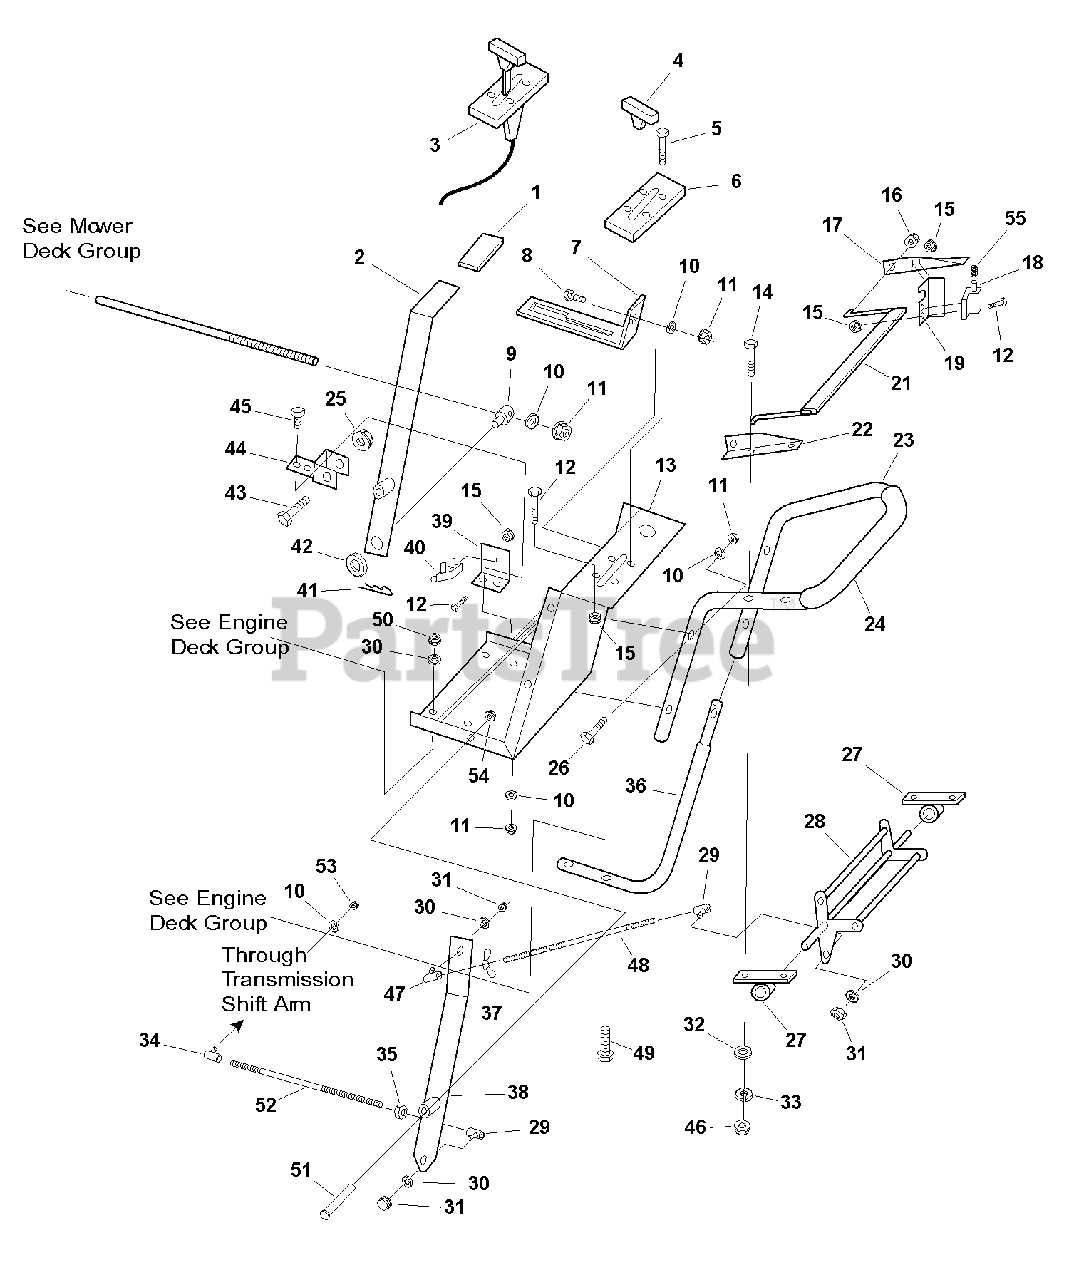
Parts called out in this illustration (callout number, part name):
1	Handle grip
2	Blade Clutch Engagement Lever
3	Throttle Control Cable Assembly, 13 HP Honda
3	Throttle Control Cable Assembly, 15 HP Kawasaki
3	Throttle Control Cable assembly, 9 HP Briggs
4	Throttle Control, T-Handle
5	Rivet, 3/16
6	Throttle Speed Indicator Plate
7	Blade Engage Lever Lock Bracket
8	Capscrew, Hex Head, 5/16-18 x 3/4
9	Rod, Fitting End
10	Lockwasher, 5/16
11	Nut, Hex, 5/16-18
12	Screw, 8-32 x 3/4
13	Control Deck & Dash Panel
14	Capscrew, Hex Head, 1/4-20 x 1-3/4
15	Nut Assembly, 8-32
16	Push Nut, 5/16
17	Safety Bar Pivot Bracket, Left
18	Safety Switch
19	Safety Switch Mounting Bracket
22	Safety Bar Pivot Bracket, Right
23	Upper Handle
24	Foam Handle Cover
25	Nut, Hex Flangelock, 1/2-13
26	Capscrew, Hex Head, 5/16-18 x 1-1/2
27	Bearing, 3/4 ID
28	Drive Engagement Bar
29	Ball Joint, 3/8-24, LH
30	Lockwasher, 3/8
31	Nut, Jam, 3/8-24
32	Flatwasher, 1/4
33	Lockwasher, 1/4
34	Ball Joint, 5/16-24
35	Nut, Hex Jam, 3/8-24, LH
36	Lower Handle
37	Nut, Wing, 3/8-24
38	Transmission Drive Intermediate Lever
39	Deck Safety Switch Bracket
40	Deck Safety Switch
41	Bridge Pin, #2
42	Washer, 3/8
43	Capscrew, Hex Head, 1/2 x 2-1/2
44	Blade Clutch Engagement Lever Bracket
45	Capscrew, Hex Head, 5/16-18 x 1
46	Nut, Hex, 1/4-20
47	Ball Joint, 3/8-24 RH
48	Transmission Engagement Rod, Upper
49	Capscrew, Hex Head, 5/16-18 x 1-3/4
50	Nut, 3/8-16
51	Bolt, Shoulder, 1/2 x 1 -3/8 to 3/8-16
52	Transmission Engagement Rod, Lower
53	Nut, Hex Jam, 5/16-24
54	Nut, Hex Centerlock, 3/8-16
55	Safety switch return spring
